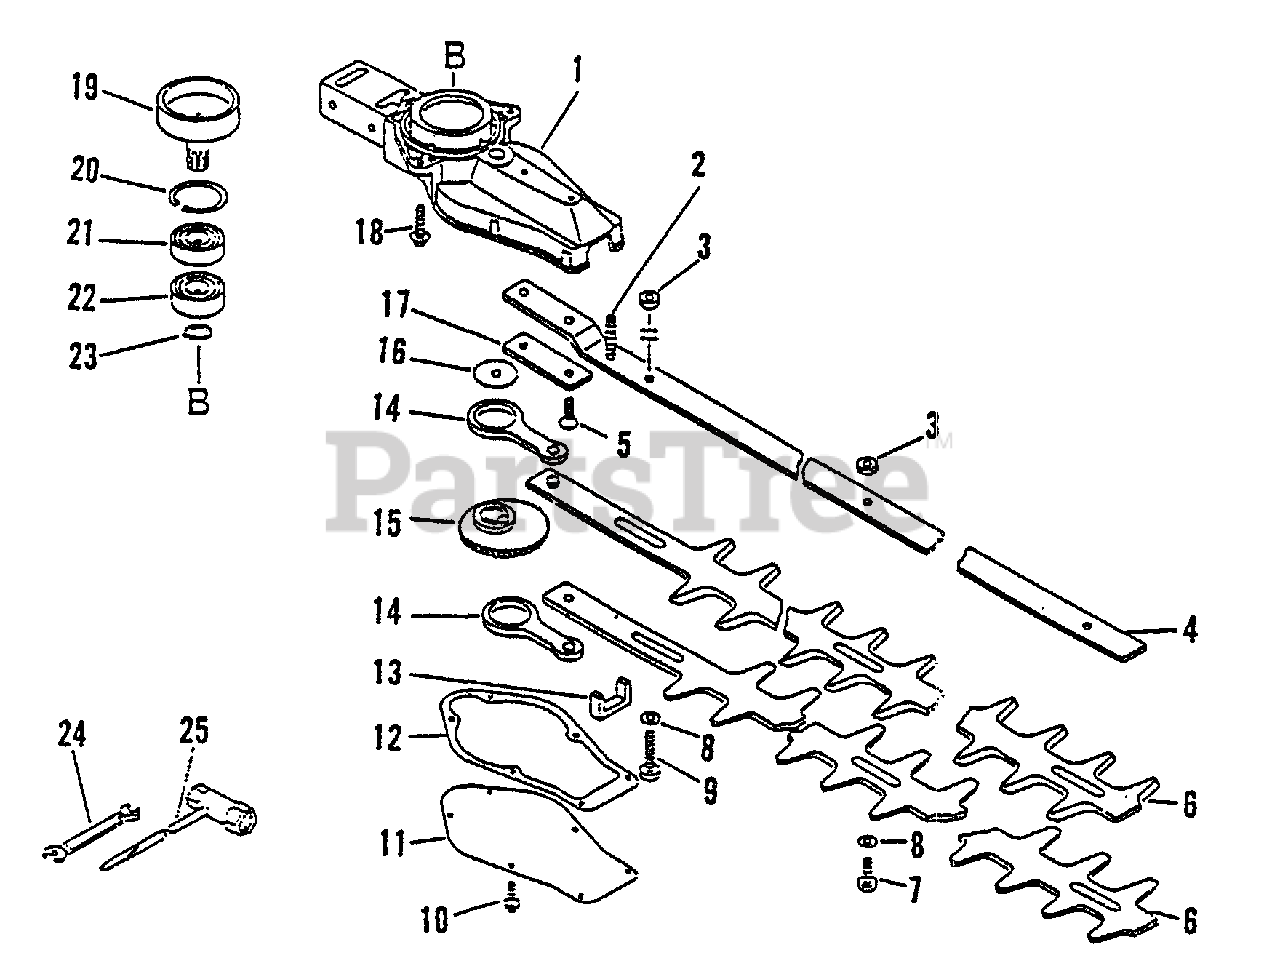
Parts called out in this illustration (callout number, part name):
1	CASE, GEAR
2	SCREW - 5X30
4	SUPPORT, BLADE
5	SCREW - 6X18
6	BLADE - 17" (43cm)
8	WASHER - 6
9	BOLT - 6X35
10	SCREW - 4X10
11	LID, GEAR CASE
12	GASKET, GEAR CASE
13	SEAL, FELT
14	ROD, CONNECTING
15	GEAR - DRIVE
18	SCREW - 5X20
19	DRUM, CLUTCH
20	RING, RETAINING - 35
21	BEARING, BALL - 6202
22	BEARING, BALL - 6202
23	RING, RETAINING - 14
24	T-WRENCH
25	SPANNER - 8X10mm
